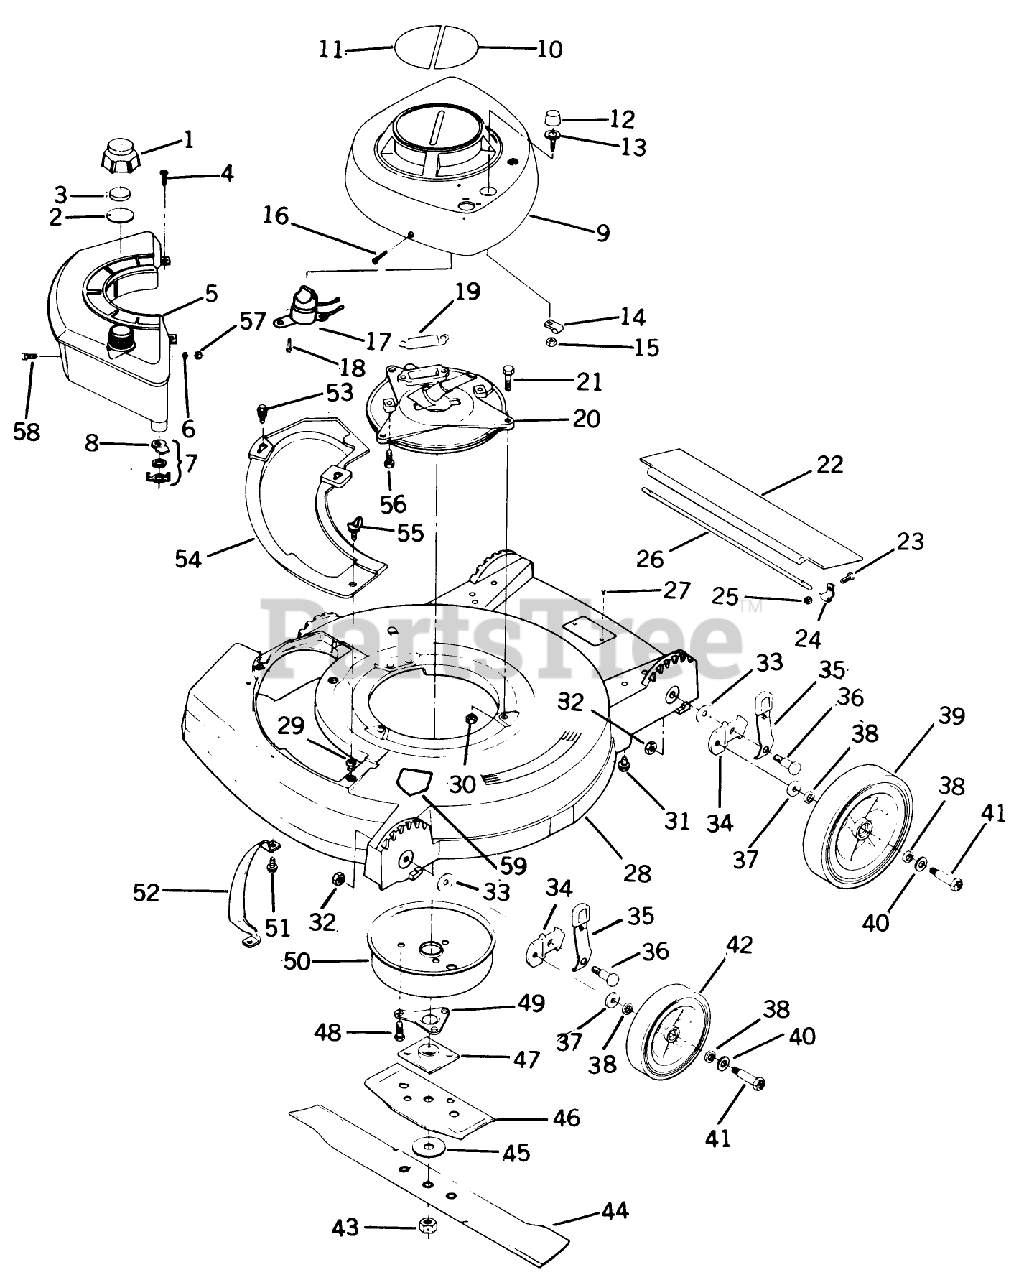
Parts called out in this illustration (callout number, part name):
2	GASKET S
3	BAFFLE - FOAM SM
4	SCREW F
7	SHUT OFF VALVE KIT
15	LOCKNUT S
16	SCREW F
21	SCREW
24	CLAMP ROD KMC
25	LOCKNUT E
26	ROD 21" ADVANCE
30	NUT-LOCK F
31	SCREW
32	LOCKNUT
33	WASHER
37	WASHER WROUGHT
38	WASHER
40	SPACER
41	BOLT WHEEL
42	WHEEL & TIRE KIT
43	NUT-BLADE
45	WASHER
47	PLATE AND COLLAR ASM
48	SCREW
49	SUPPORT F
52	BAR-TOE
55	WING SCREW LAWRE
56	SCREW V
